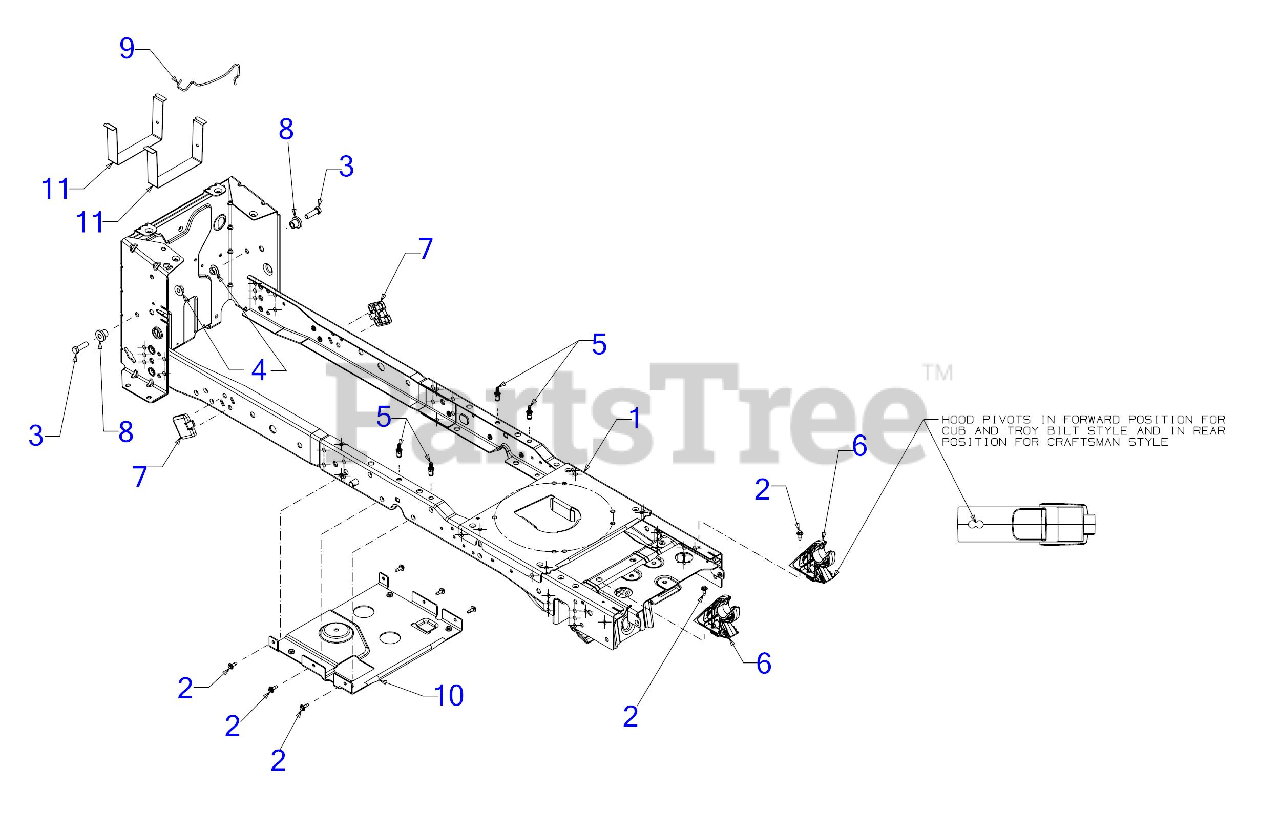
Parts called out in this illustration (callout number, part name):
1	FRAME ASSEMBLY
2	SCREW M6-1 x .625
3	SCREW 3/8-16 x 1.25 GR5
4	FLANGE LOCK NUT
5	RIVET-HEX STUD 1/4-20 FRM
6	HOOD PIVOT BRACKET
7	LIFT ROD WEAR PAD
8	SHOULDER SPACER
